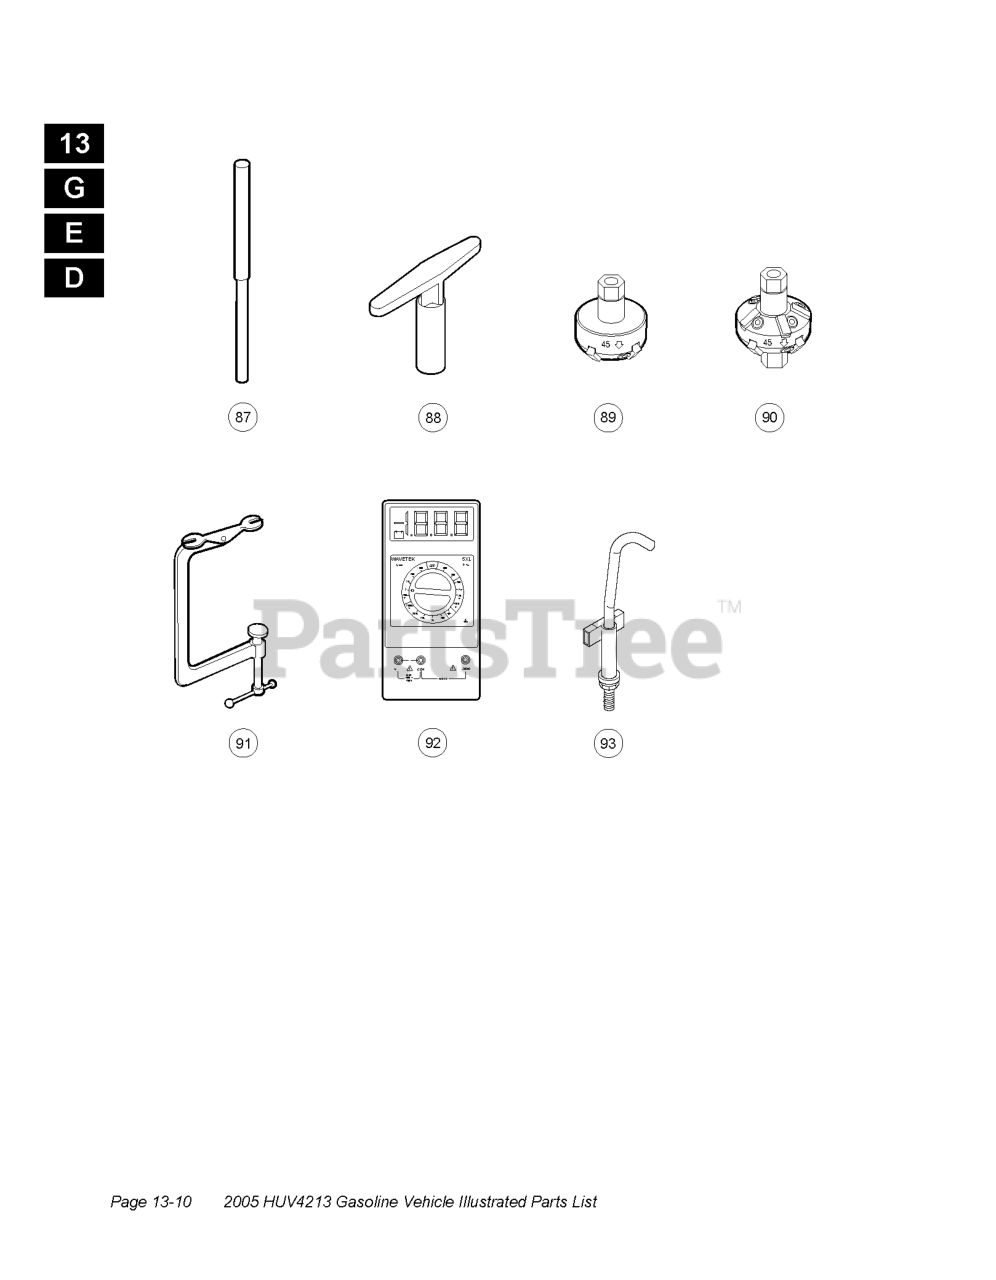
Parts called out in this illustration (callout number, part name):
86	VALVE SEAT CUTTER GUIDE
87	VALVE SEAT CUTTER "T" WRENCH
88	VALVE SEAT CUTTER 45 DEG 32 MM
89	CUTTER INTAKE VALVE ST 45/30
90	VALVE SPRING CMPR & ADAPTER
91	METER, WAVETEK VOLT-OHM
92	S/G TENSIONING TOOL
